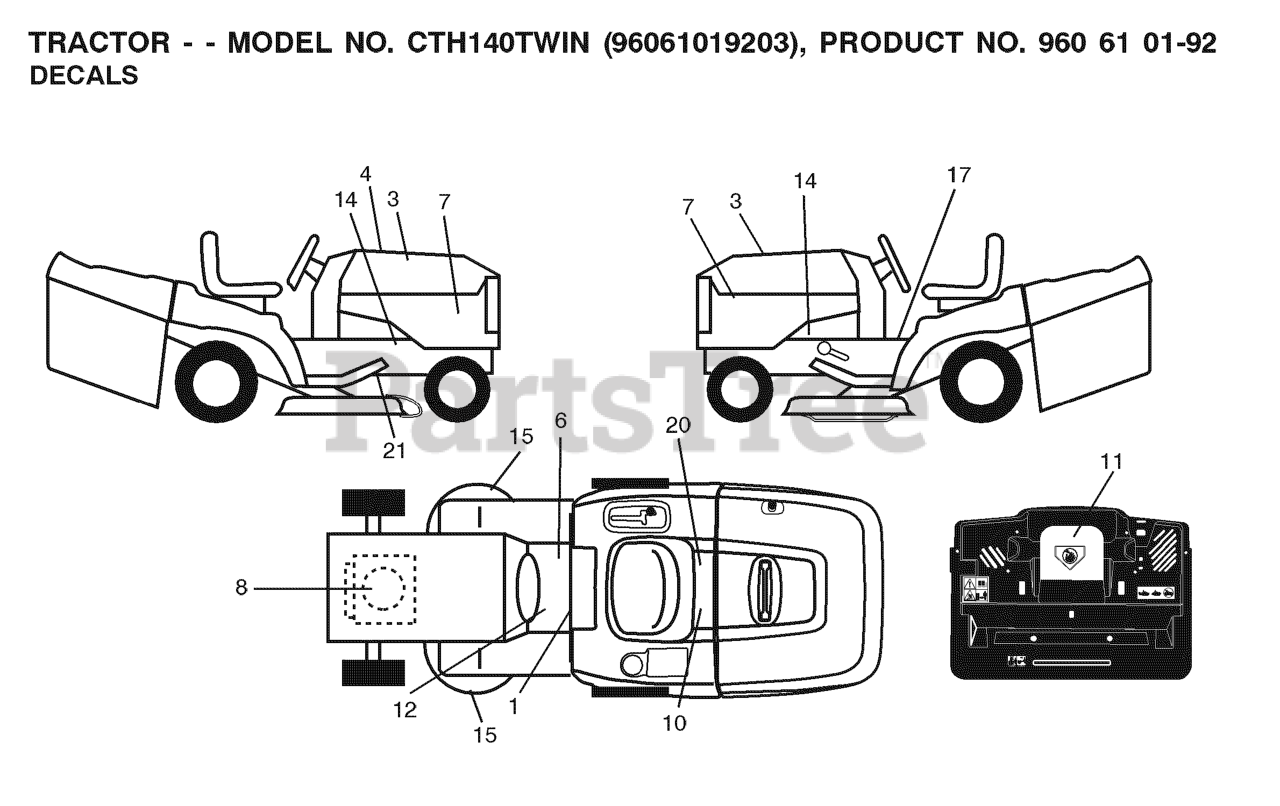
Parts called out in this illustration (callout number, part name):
1	LABEL
3	DECAL.HOOD.NAMELOGO.HUSQ
6	Decal, Fender 100 DB/CE
10	DECAL BTRY SYMBOLS
11	DECAL.INTERNATIONL.CUTFINGER
12	DECAL
17	DECAL PARK BRAKE
20	DECAL.BYPASS.FENDER.CRD.LT.YT
